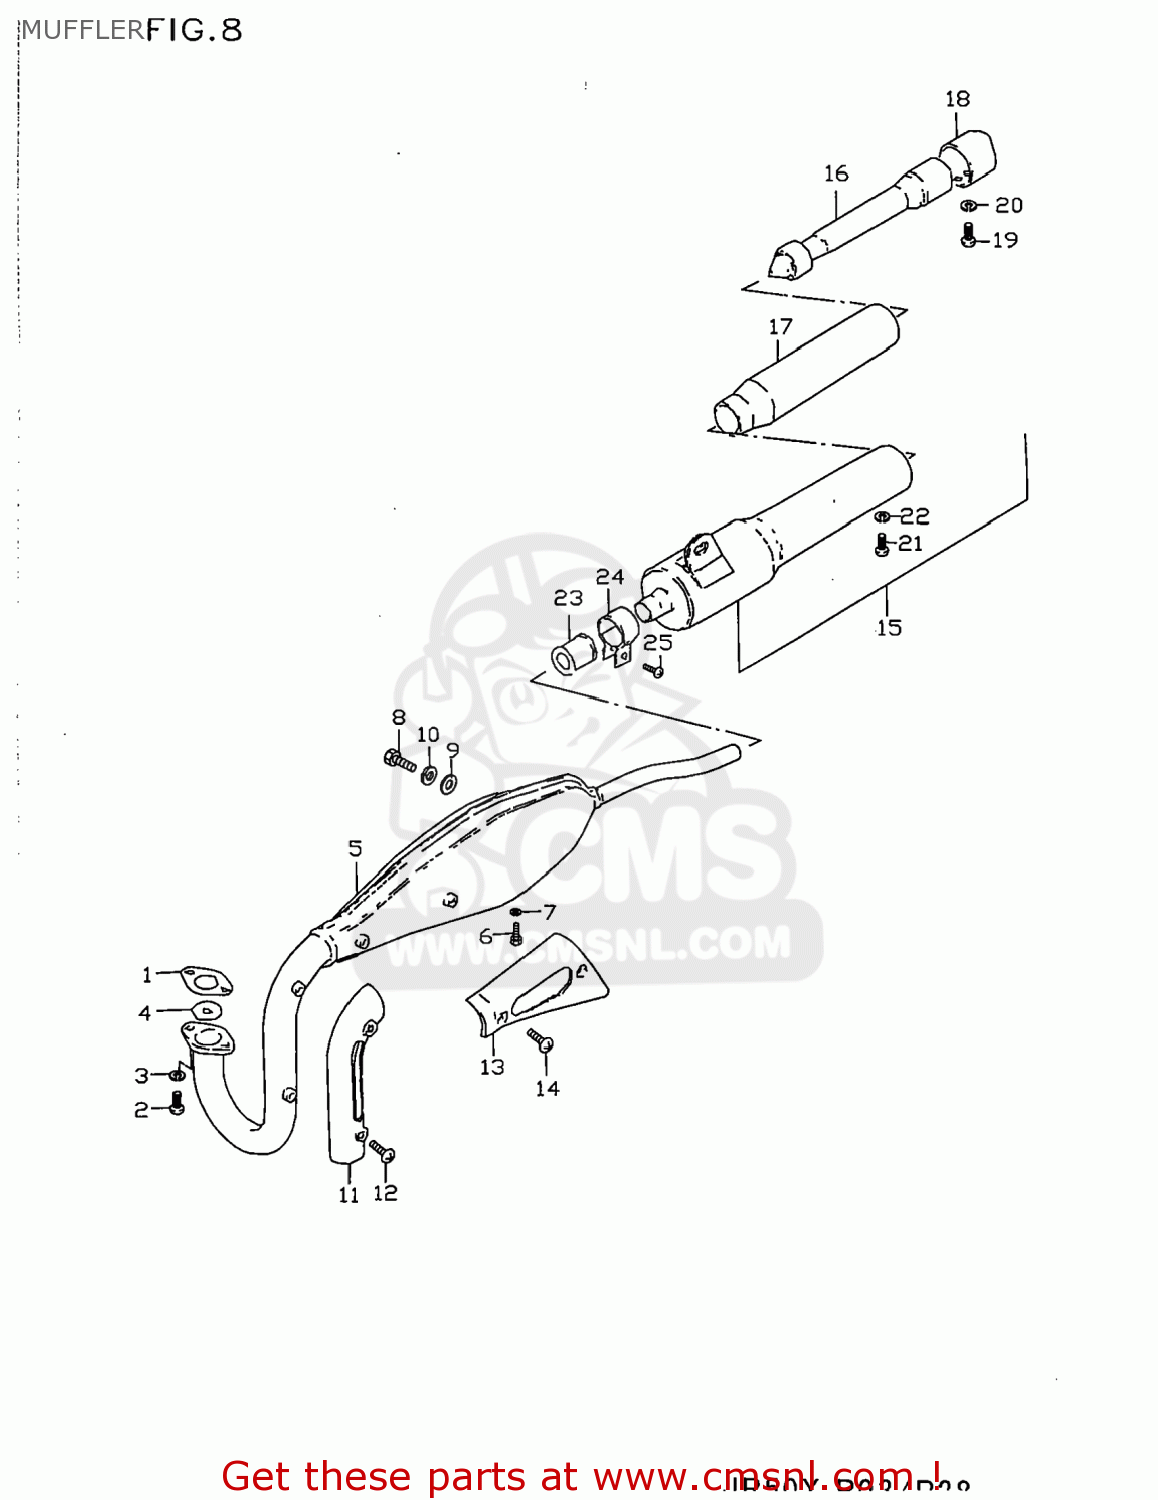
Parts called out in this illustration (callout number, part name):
1	GASKET,EXHAUST PIPE (NAS)
2	BOLT,OIL FILLE
3	LOCK WASHER
4	PLATE,EXHAUST PIPE
5	MUFFLER ASSY
6	BOLT
7	WASHER
8	BOLT
9	WASHER (8.2X20X1.6)
10	LOCK WASHER
11	COVER,EXHAUST PIPE
12	SCREW (M5X6)
13	COVER,MUFFLER
14	SCREW (M5X6)
15	MUFFLER ASSY,2ND
16	TUBE,CLEAN OUT
17	SHELL,ARRESTER
18	CUTTER,MUFFLER TAIL
19	SCREW
20	LOCK WASHER
21	SCREW 6X16
22	LOCK WASHER
23	CONNECTOR,MUFFLER
24	CLAMP
25	SCREW 6X16
